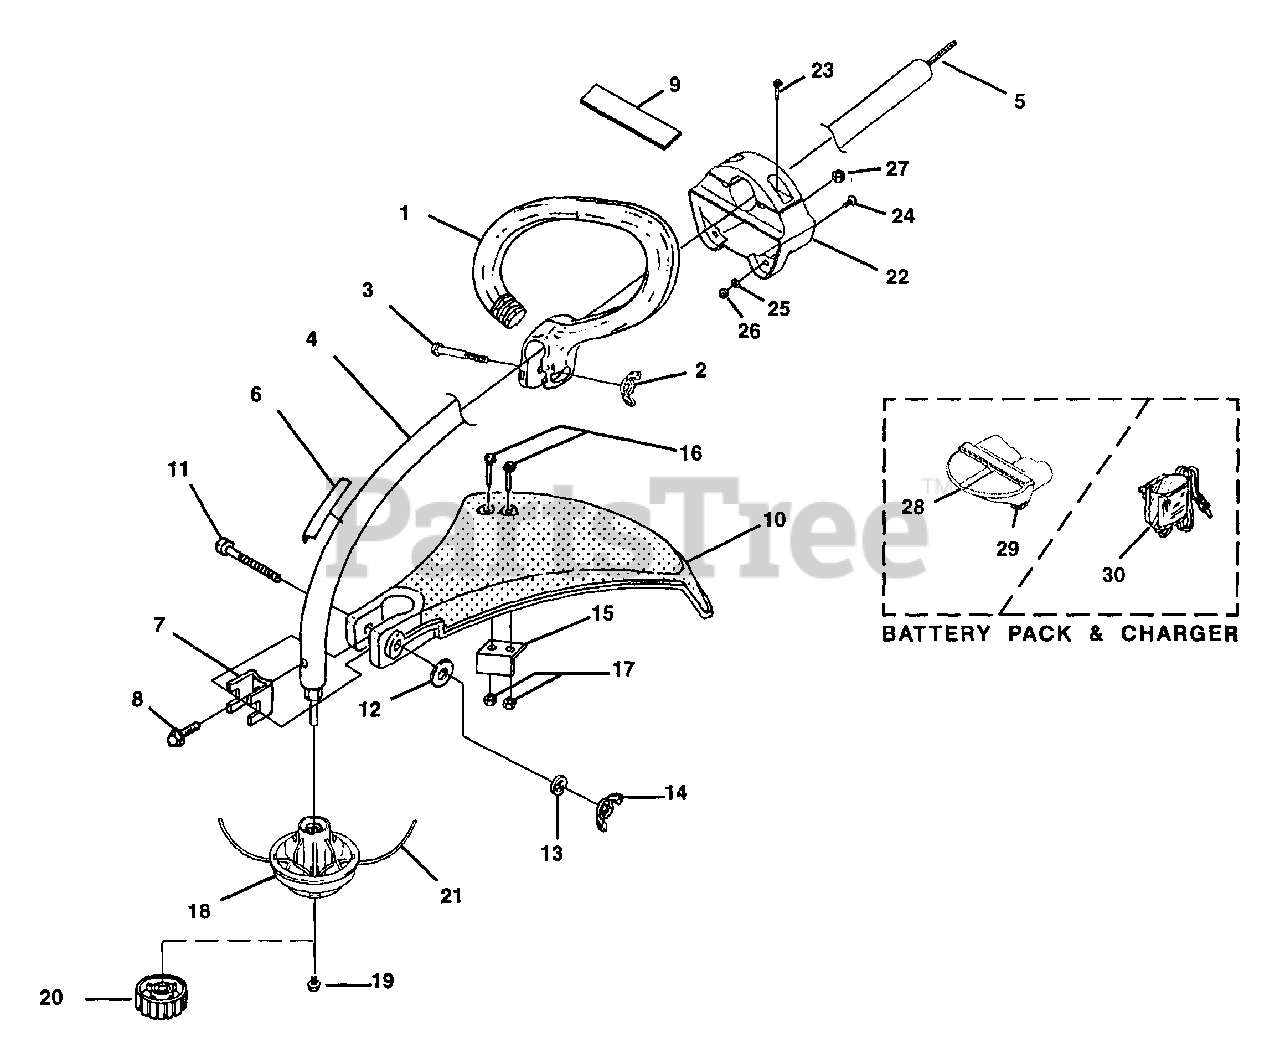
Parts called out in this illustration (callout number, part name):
1	HANDLE - Anti-Vibe
2	NUT-Wing, Washer Faced (1/4-20)
3	SCREW-Cap Hex Hd.
4	DRIVESHAFT HOUSING ASSY.
5	SHAFT-Flexible
6	DECAL-Warning
7	CLAMP
8	SCREW-Sems Hex Hd. (#10-24 X 3/8")
9	GROMMET, Isolator
10	DEFLECTOR & BLADE KIT (55 Deg.)
11	SCREW-Cap Hex Hd. (10-24 X 2")
12	WASHER-Flat (1/4")
13	WASHER-Lock (1/4")
14	NUT-Wing, Washer Faced (1/4-20)
15	BLADE-Cut-Off
16	SCREW-Mech. Hex Hd. (10-24 X 7/8")
17	NUT-Hex (10-24)
18	STRINGHEAD-Pro-Cut w/line
19	SCREW-Stringhead Retainer
20	RETAINER-Spool (RH Thread, Black)
21	LINE-Replacement
22	BATTERY ENCLOSURE
23	SCREW
24	SCREW
26	NUT-Spanner
28	BATTERY PACK
29	KNOB-Battery Pack
30	BATTERY CHARGER
